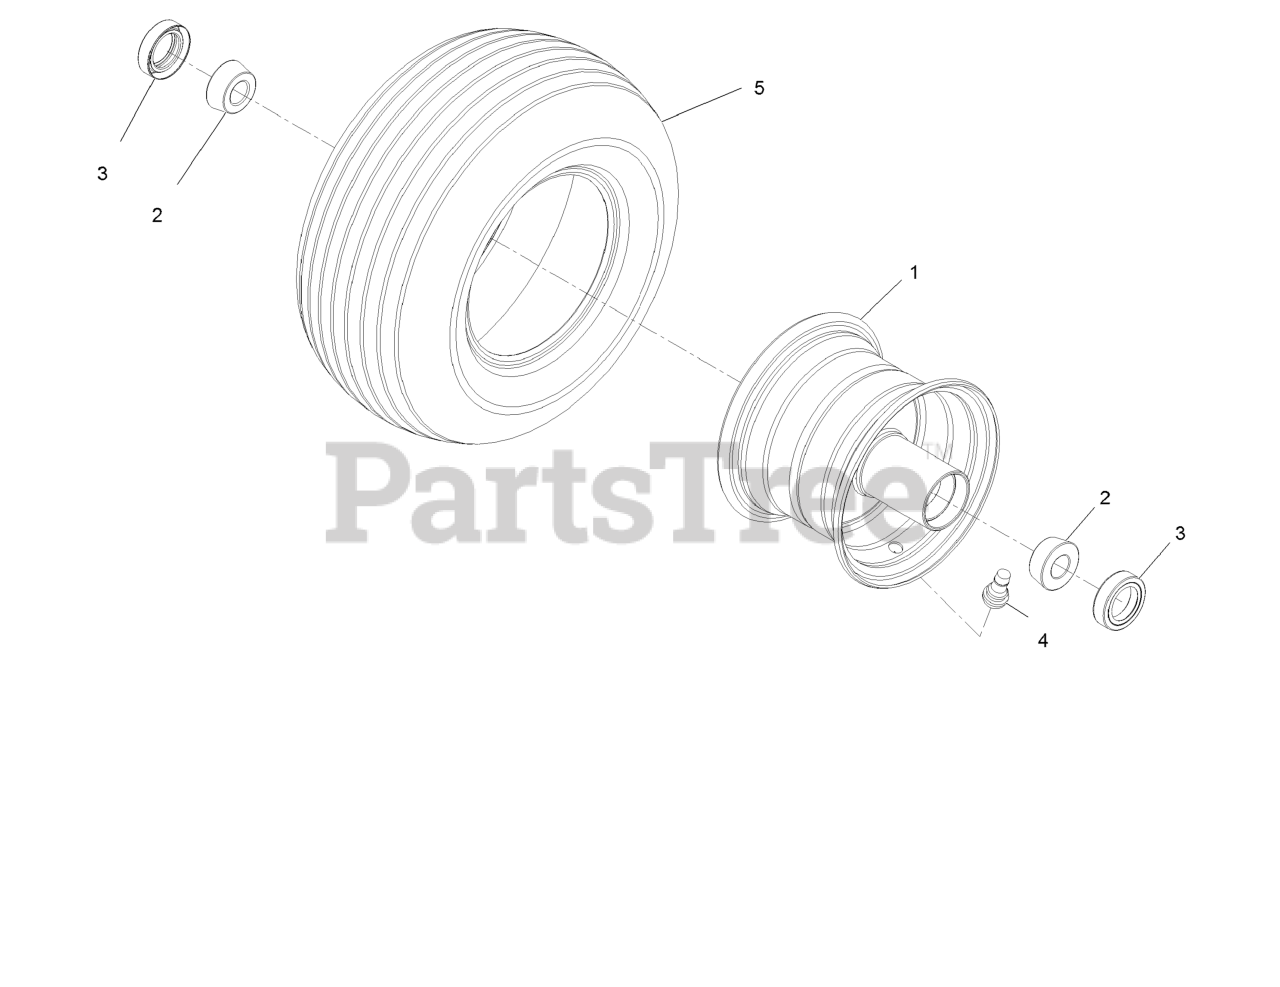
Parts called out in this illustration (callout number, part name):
1	RIM-6 X 4.5
2	BEARING-CONE, TAPERED ROLLER
3	SEAL-CASTER
4	VALVE
5	TIRE-RIB
